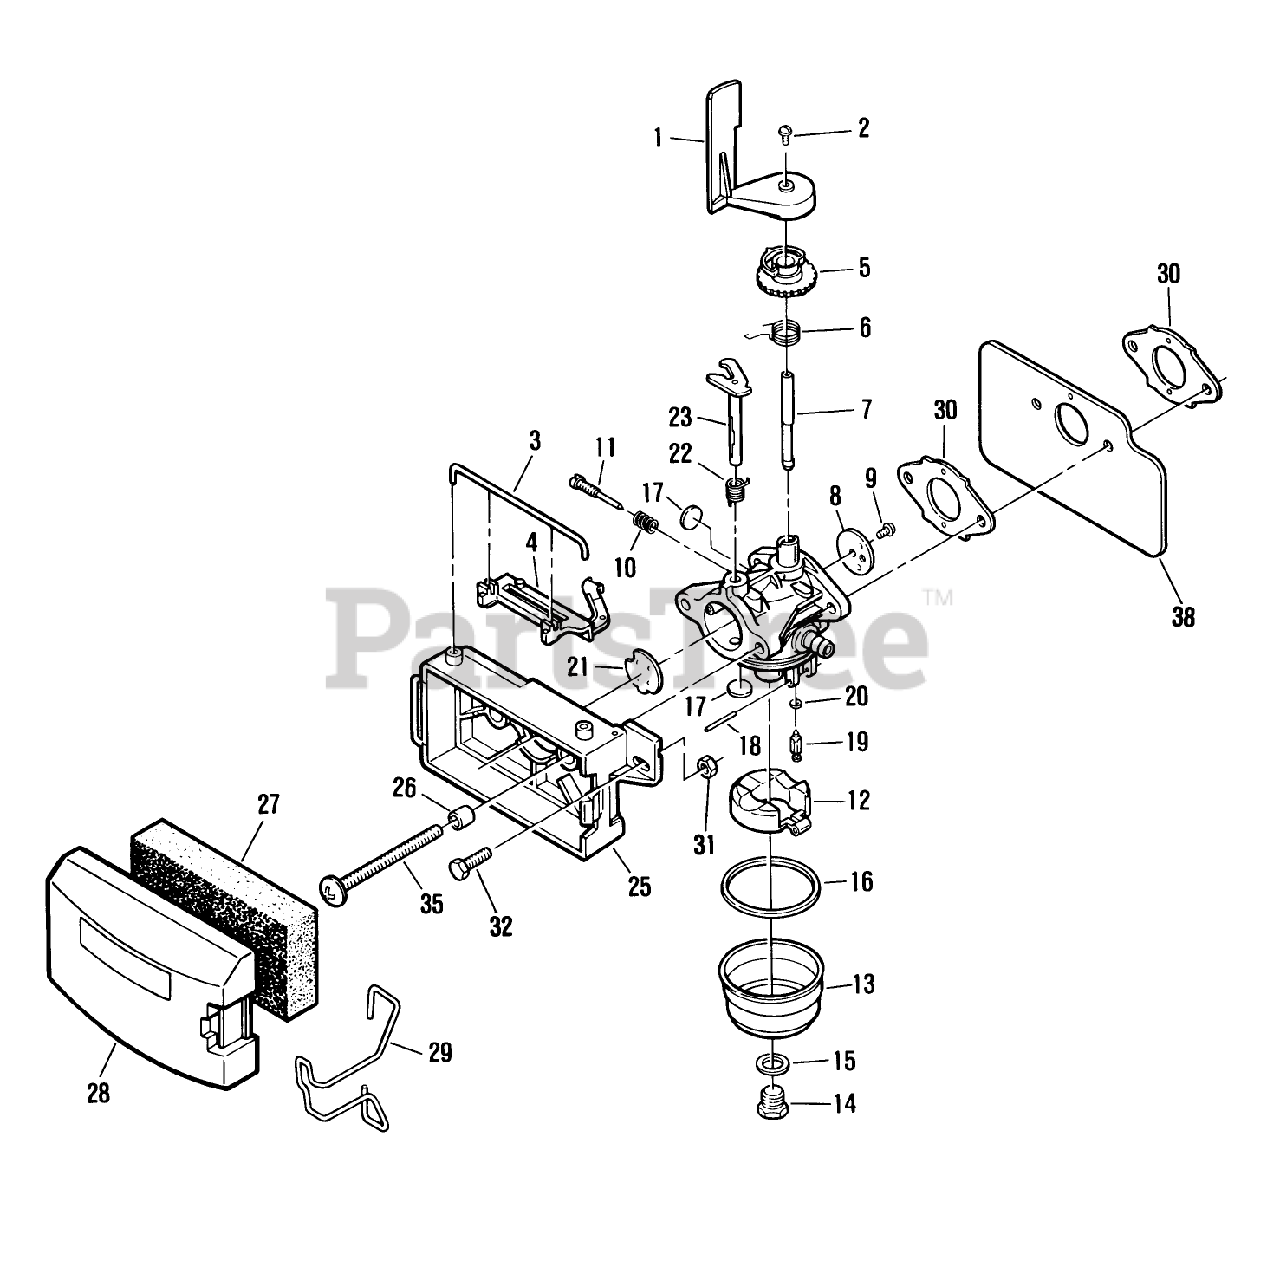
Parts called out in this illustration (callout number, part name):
1	AIR VANE F
2	SCREW F
3	RETAINER
5	COLLAR A/VAVE F
7	Shaft-Throttle
8	Valve-Throttle
9	Screw-Throttle Valve
10	Spring-Idle Needle
11	Needle-Idle
13	Bowl-Fuel
14	Screw-Bowl Retainer Kit-Gasket
15	Gasket-Bowl Retainer
16	Gasket-Fuel Bowl
17	Plug-Welch
18	Shaft-Float
19	Valve-Inlet Needle
20	Seat-Valve Kit-Gasket
21	Valve-Choke
22	Spring-Choke Return
23	Shaft-Choke
29	RETAINER-COVER, FILTER
30	GASKET CARB S
32	Screw (Throttle Cable)
